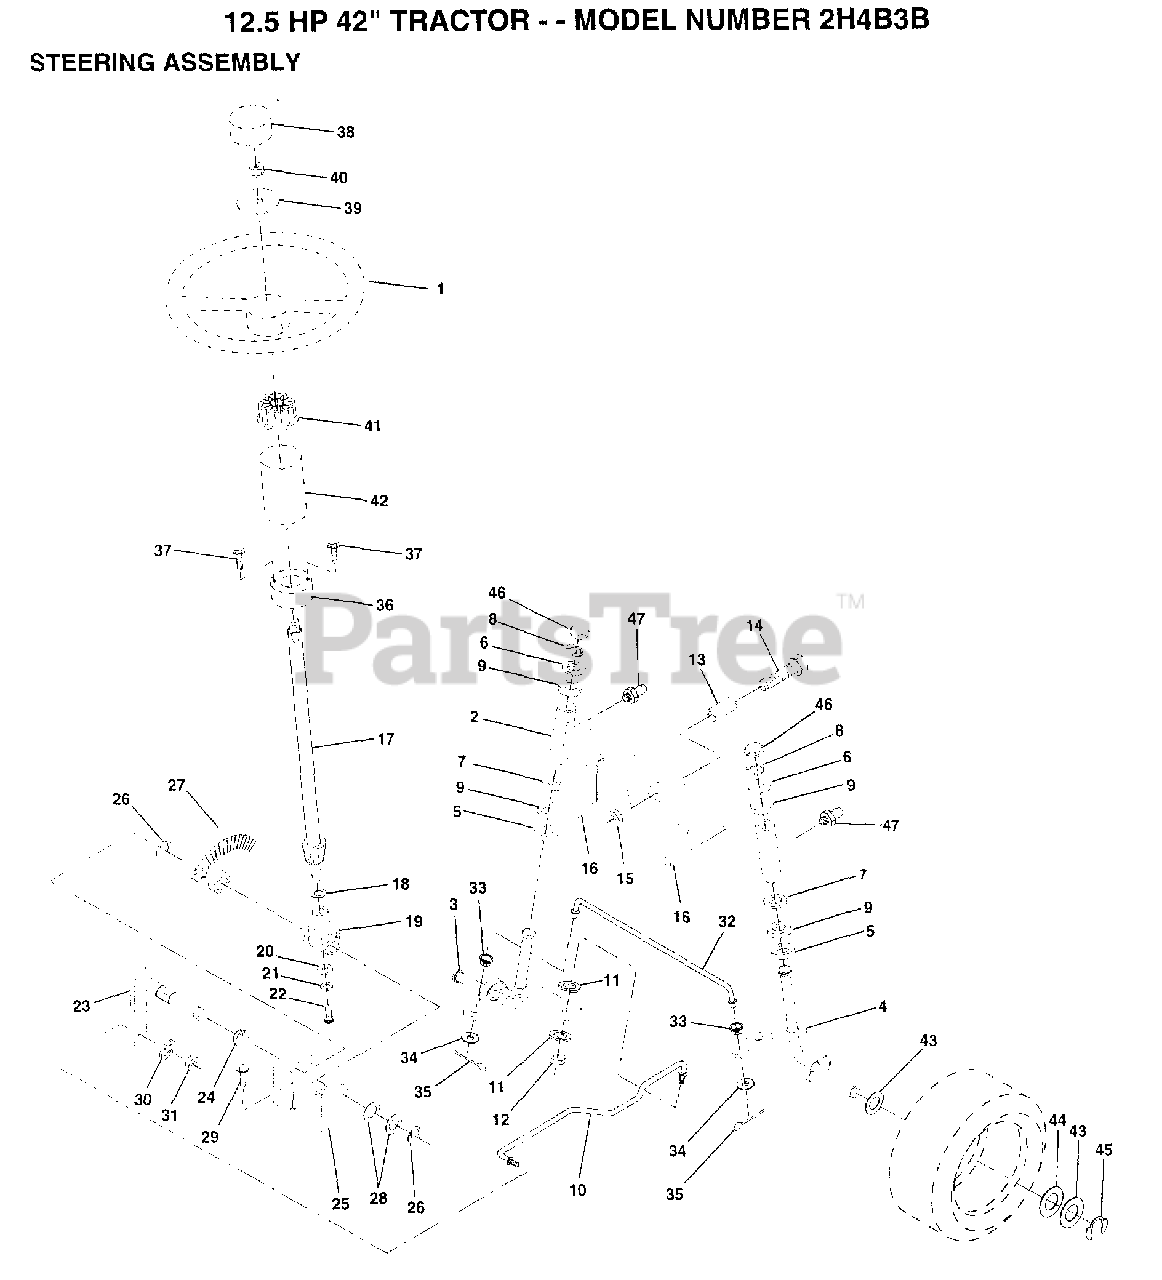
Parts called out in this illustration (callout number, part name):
2	AXLE ASM FRONT
3	SPINDLE LH
4	SPINDLE RH
5	WASHER .T
6	WASHER
7	WASHER
8	RING
9	COL. SRTG. BEAR.
11	LOCKWASHER
13	BEARING
14	BOLT HEX 5/8-11
15	"NUT-LOC,FLANGE LT"
16	AXLE PIN
17	SHAFT ASM
18	THRUST WASHER
19	SUPPORT.SHAFT
21	LOCKWASHER
22	"SCREW,SPECIAL"
24	NYLINER T
25	"BRKT,STEERING"
26	RING
27	GEAR SECTOR
28	WASHER .T
29	SCREW
30	LOCKWASHER
32	TIE ROD
33	BUSHING.DRAGLINK
34	WASHER
35	COTTER PIN
38	ST WHL INSERT CAP
39	WASHER T
40	GRIPCO NUT
41	ADAPTER-WHEEL LT
42	"TUBE, STR SHAFT"
43	WASHER
44	WASHER
45	RING
46	CAP
47	ZERK M
